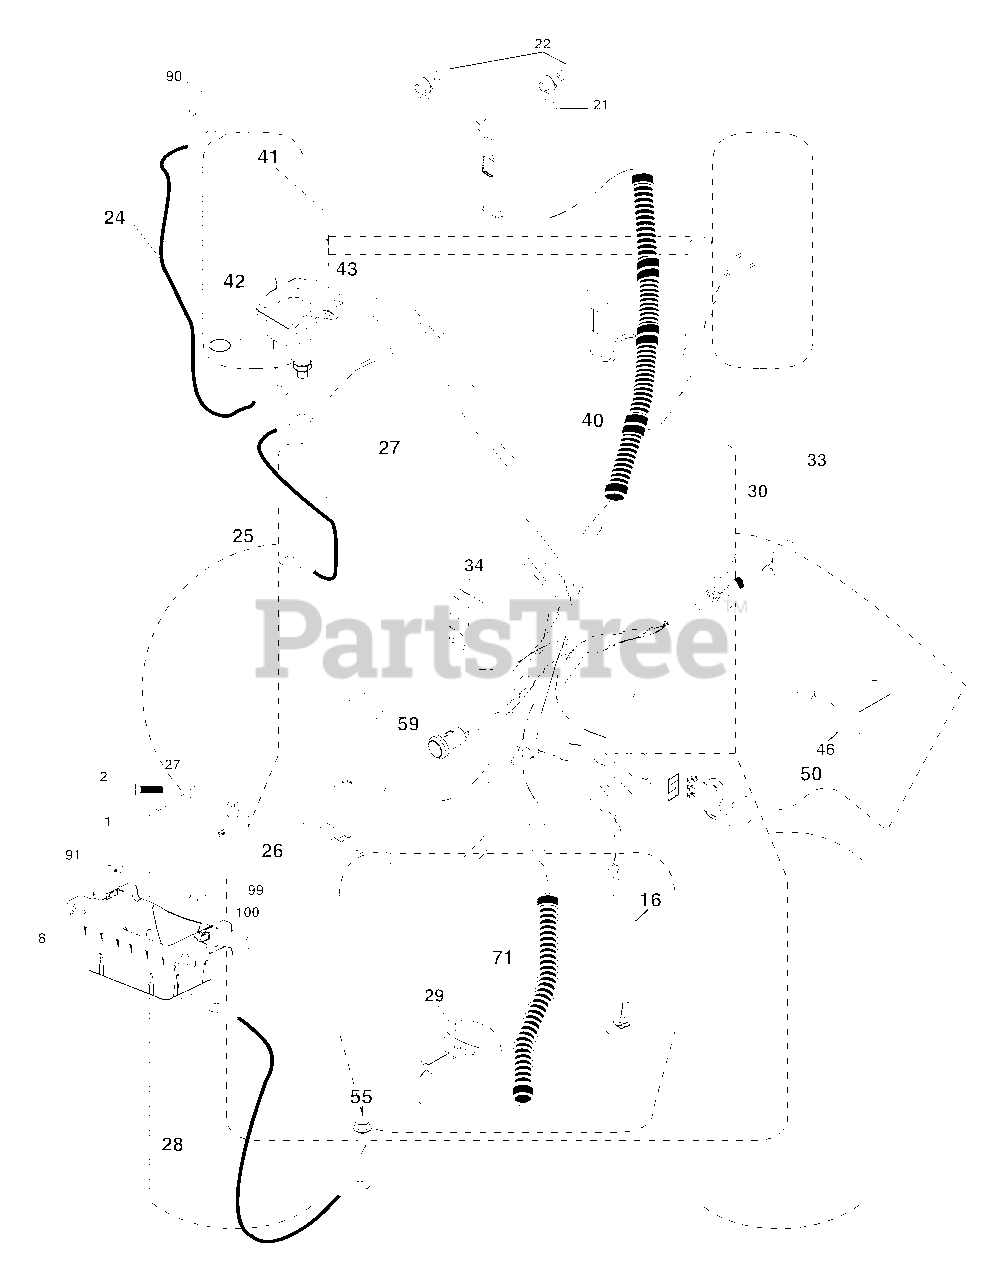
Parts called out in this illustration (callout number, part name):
1	Battery
2	Bolt Hex Hd 1/4-20 unc x 3/4
8	Battery Box
16	Switch Interlock
21	Harness Socket Light
22	Bulb, Light # 1156
24	Cable Battery
25	Cable Starter
27	Nut Keps Hex 1/4-20 unc
28	Cable Ground 21" Blk 6 Ga.
29	Switch Seat
30	Switch Ign
33	Key Ign Molded Generic
34	Switch Light/Reset
40	Harness Ign
41	Screw Thd Cut 1/4-20 x 1/2
42	Cover Terminal Red
43	Solenoid
46	Gauge Hourmeter
50	Switch PTO
55	Screw Thdrol 5/16-18 x 3/4
59	Outlet 12-Volt
71	Harness Ign. Dash
90	Cover Terminal Battery
91	Strap Battery
99	Screw Hexwsh Thdrol 1/4-20 x 3/4
100	Washer 9/32 x 7/8 x 16 Ga.
